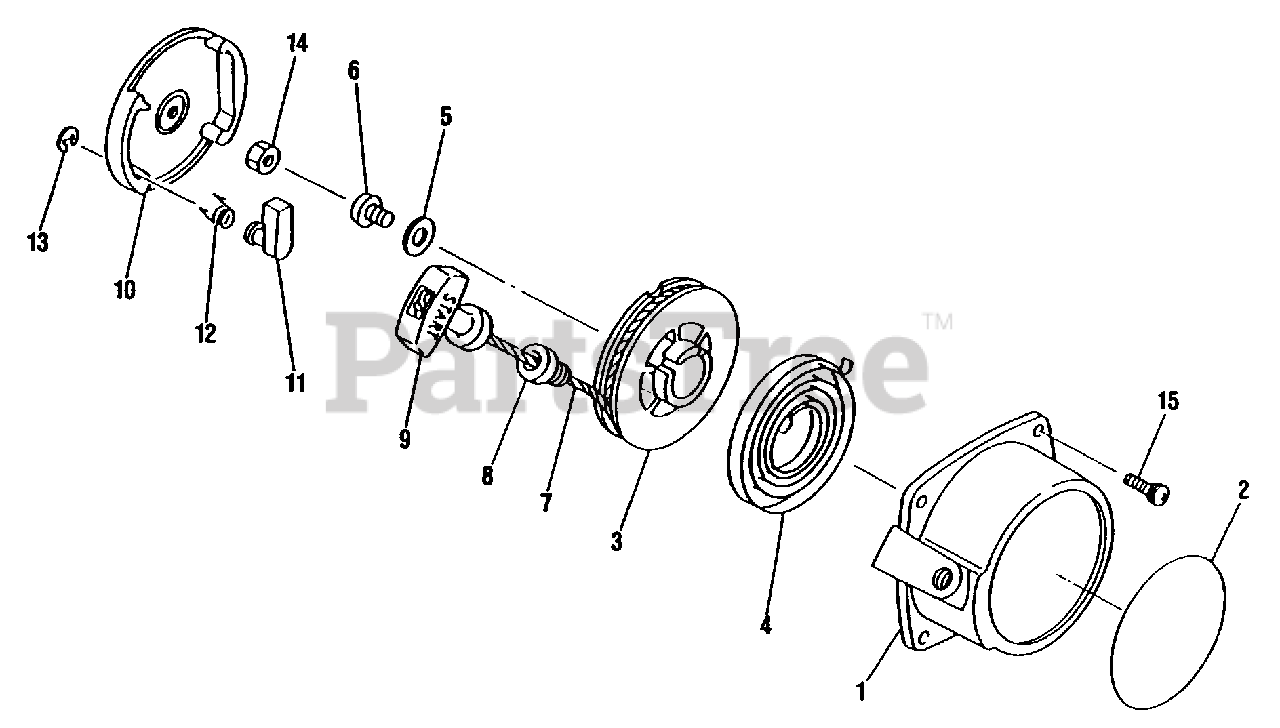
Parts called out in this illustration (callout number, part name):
1	CASE, STARTER
2	NAME PLATE
3	REEL, ROPE
4	SPRING, REWIND
5	WASHER
6	SCREW
7	ROPE, STARTER
8	GUIDE, ROPE
9	GRIP, STARTER
10	REEL, ROPE
11	RATCHET
12	SPRING, RETURN
13	RING, RETAINING
14	NUT
15	SCREW - 4X12
